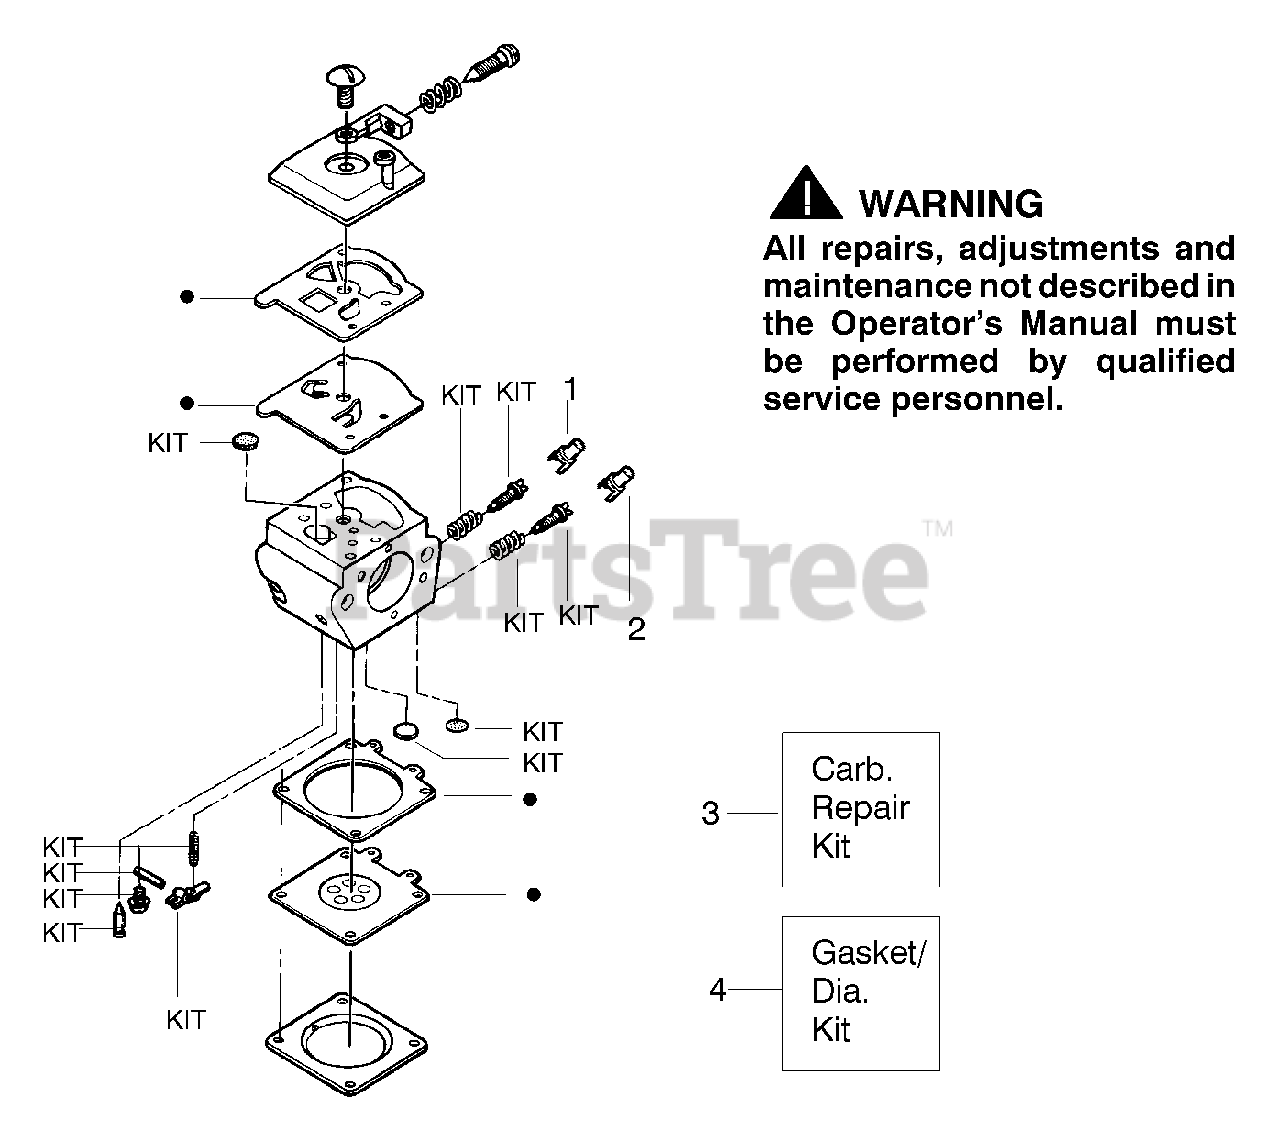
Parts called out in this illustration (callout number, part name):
1	Limiter Cap High (brown)
2	Limiter Cap Low (tan)
3	Carburetor Repair Kit
4	Gasket Diaphragm Kit
